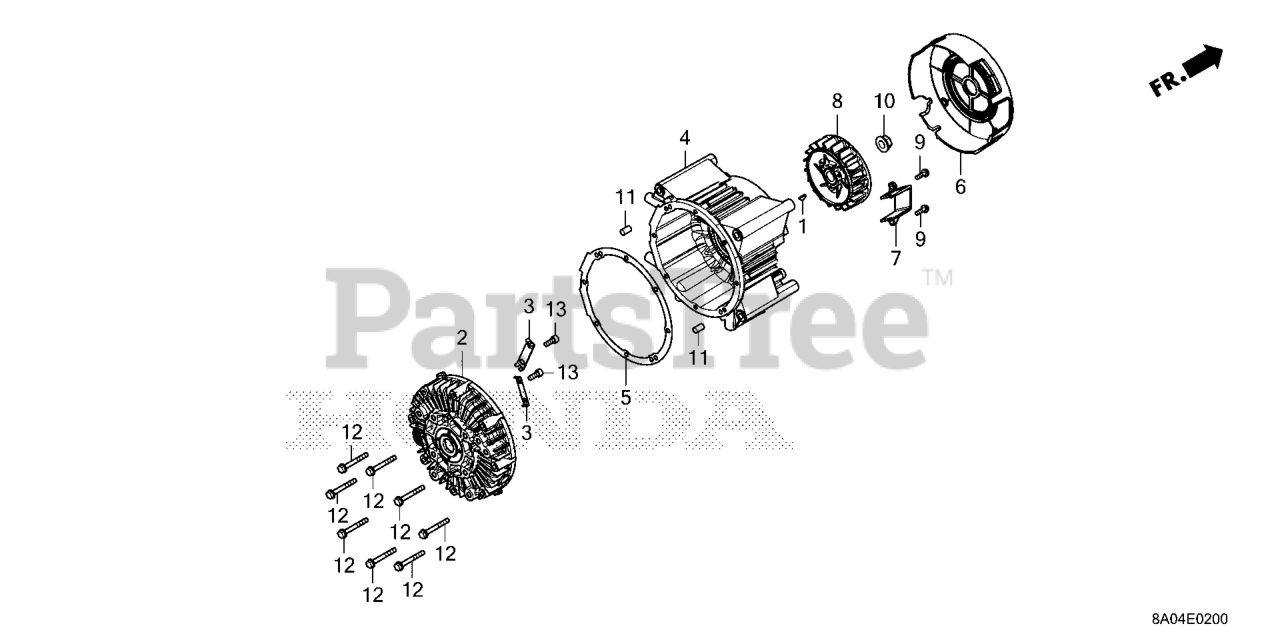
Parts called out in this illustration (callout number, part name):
1	KEY (13X12)
2	HOUSING, MOTOR
3	STAY, MOTOR HARNESS
4	HOUSING, MOTOR
5	PAKING, HOUSING
6	COVER, FAN *NH1*
8	FAN, COOLING
9	BOLT, FLANGE (5X16)
10	NUT, FLANGE (12MM)
11	PIN B, DOWEL (6X10)
12	BOLT, FLANGE (6X50)
13	BOLT, SOCKET (6X16)
